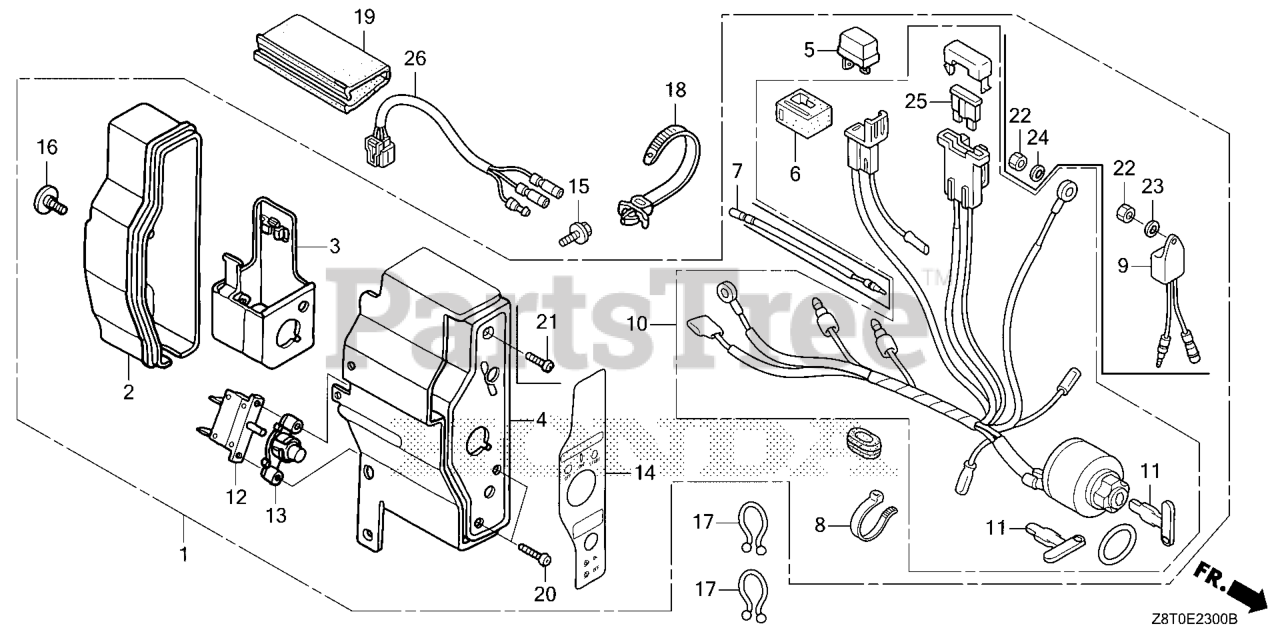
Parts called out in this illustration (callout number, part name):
1	BOX ASSY., CONTROL *NH1* (EXTERNAL) (BLACK)
2	CASE, CONTROL
3	BRACKET, CASE MOUNTING
4	PANEL, CONTROL *NH1* (BLACK)
5	RECTIFIER ASSY., SILICON (SHINDENGEN)
6	SUSPENSION, CONNECTOR
8	BAND
10	SWITCH ASSY., COMBINATION
11	KEY
12	PROTECTOR, CIRCUIT (1.0A)
13	LENS ASSY., PROTECTOR
14	MARK, CONTROL BOX (EXTERNAL)
15	BOLT, FLANGE (6X12) (CT200)
16	SCREW, SPECIAL (6X12)
17	CLIP, PURSE LOCK
18	STRAP, CABLE (118MM) *NH1L* (Honda Code 1170653). (BLACK)
19	TUBE, FASTENER (30)
20	SCREW, PAN (3X12)
25	FUSE, BLADE (5A)
26	WIRE HARNESS ASSY., ENGINE (SEL)
